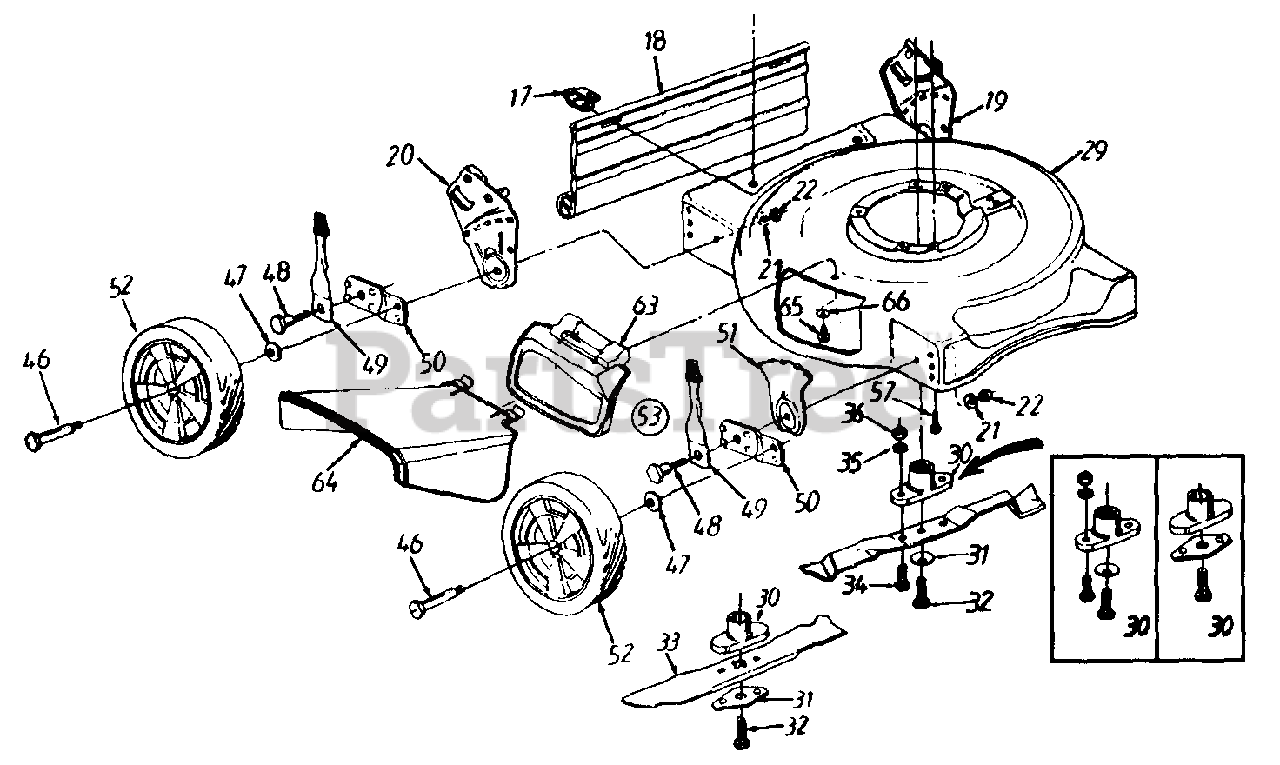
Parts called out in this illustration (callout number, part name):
17	Hinge Clip
18	Rear Flap
21	Bell-Wash. .39" I.D. x 1.38"
22	Hex Nut 3/8-16 Thd.
29	20" Deck Assy.
30	Blade Adapter Kit
31	Bell-Wash. .46" I.D.
32	Hex Bolt 7/16-20 x 1.5" Lg.
33	20" Mulch Blade
34	Hex Bolt 3/8-24 x 1" Lg.
35	L-Wash. 3/8" I.D.
36	Hex Nut 3/8-24 Thd.
47	Bell-Wash. .400" I.D. x .88"
48	Shld. Bolt .50" Dia. x .357"
49	Spring Lever Assy. w/Knob
51	Height Adj. Plate
52	Wheel Assy. Comp.
53	Ht Adj. Assy. Comp. R.F. & L.R.
57	Hex L-Wash. Hd. Scr. 3/8-16 x 1.0" Lg.
63	Mulching Plug
64	Chute Deflector
65	Bell-Wash. 1/4" I.D.
66	Hex Wash. Hd. TT-Tap Scr. 1/4-20 x .5" Lg.
